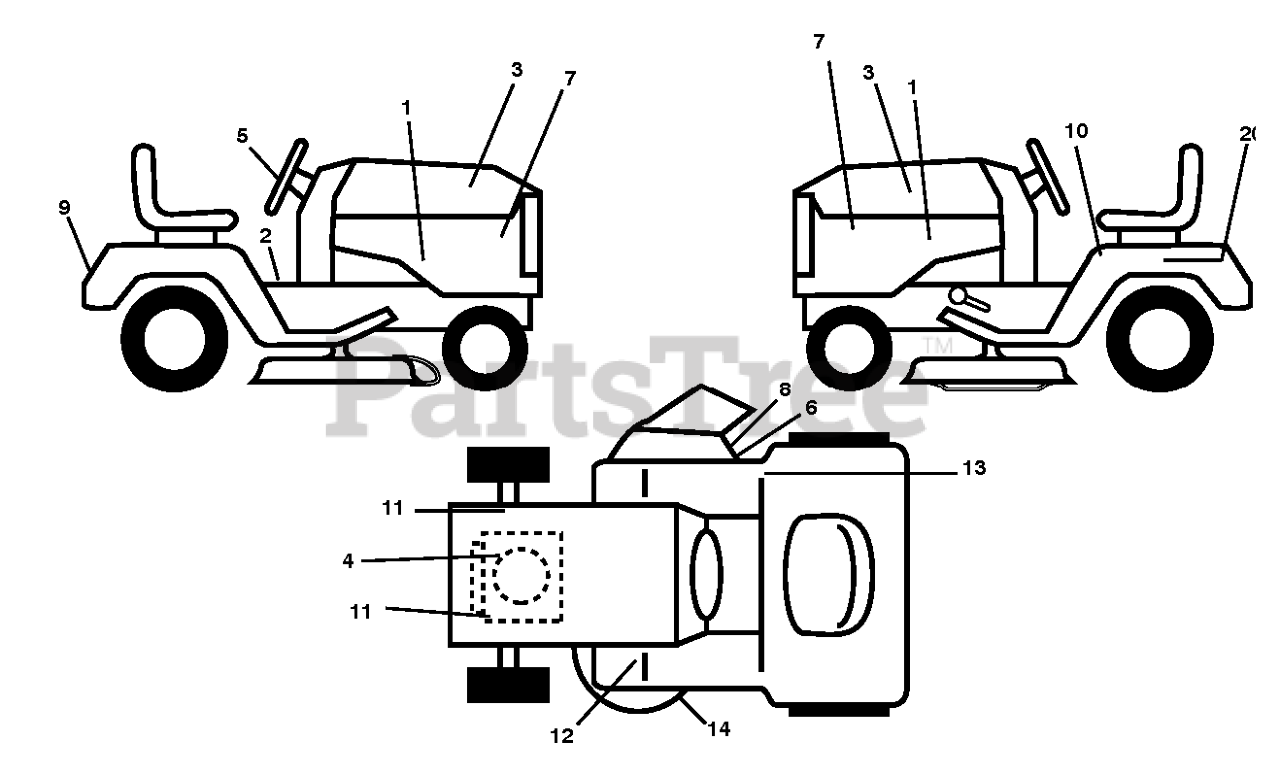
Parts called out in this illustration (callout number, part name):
2	DECAL PARK BRAKE
4	DECAL
5	DECAL.STEERING.HUSQ.BLUE
6	DECAL, DEFLECT WARNING
7	DECAL.HOOD.HUSQVARNA.INTERNATI
8	DECAL.INTERNATIONL.CUTFINGER
10	LABEL
12	DECAL
13	DECAL
14	DECAL.V-BELT.SCHEMATIC.36/38/9
20	DECAL BTRY SYMBOLS
